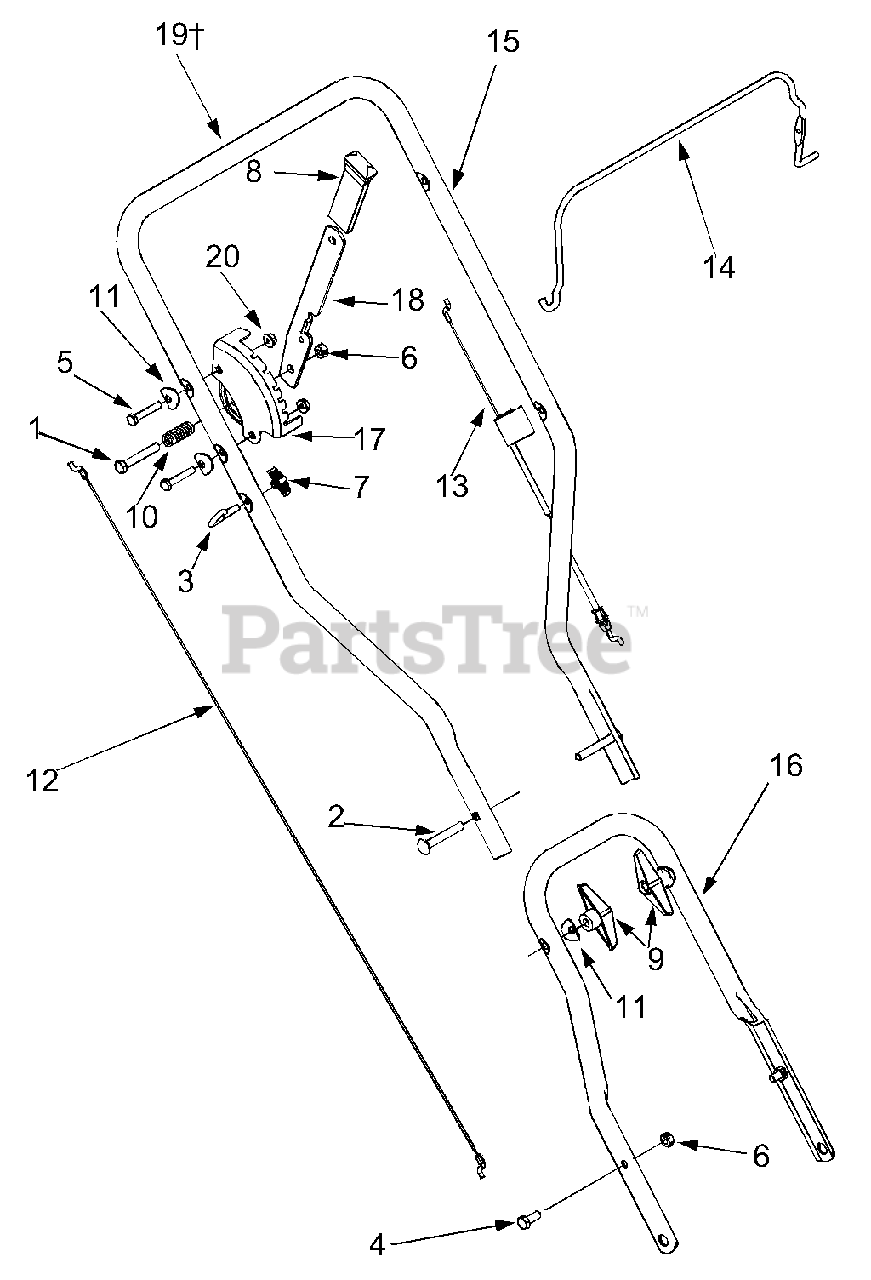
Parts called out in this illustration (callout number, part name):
1	Screw, 5/16-18
2	Screw, 5/16-18
3	Eye Bolt
4	Screw, 5/16-18
5	Screw
6	Hex Lock Nut, 5/16-18
7	Wing Nut
9	Wing Knob
10	Compression Spring
11	Saddle Washer,.320 ID x.93 OD
12	Wheel Adjustment Cable
13	Control Cable (Tecumseh)
19	Foam Grip
20	Hex Flange Nut, 1/4-20
